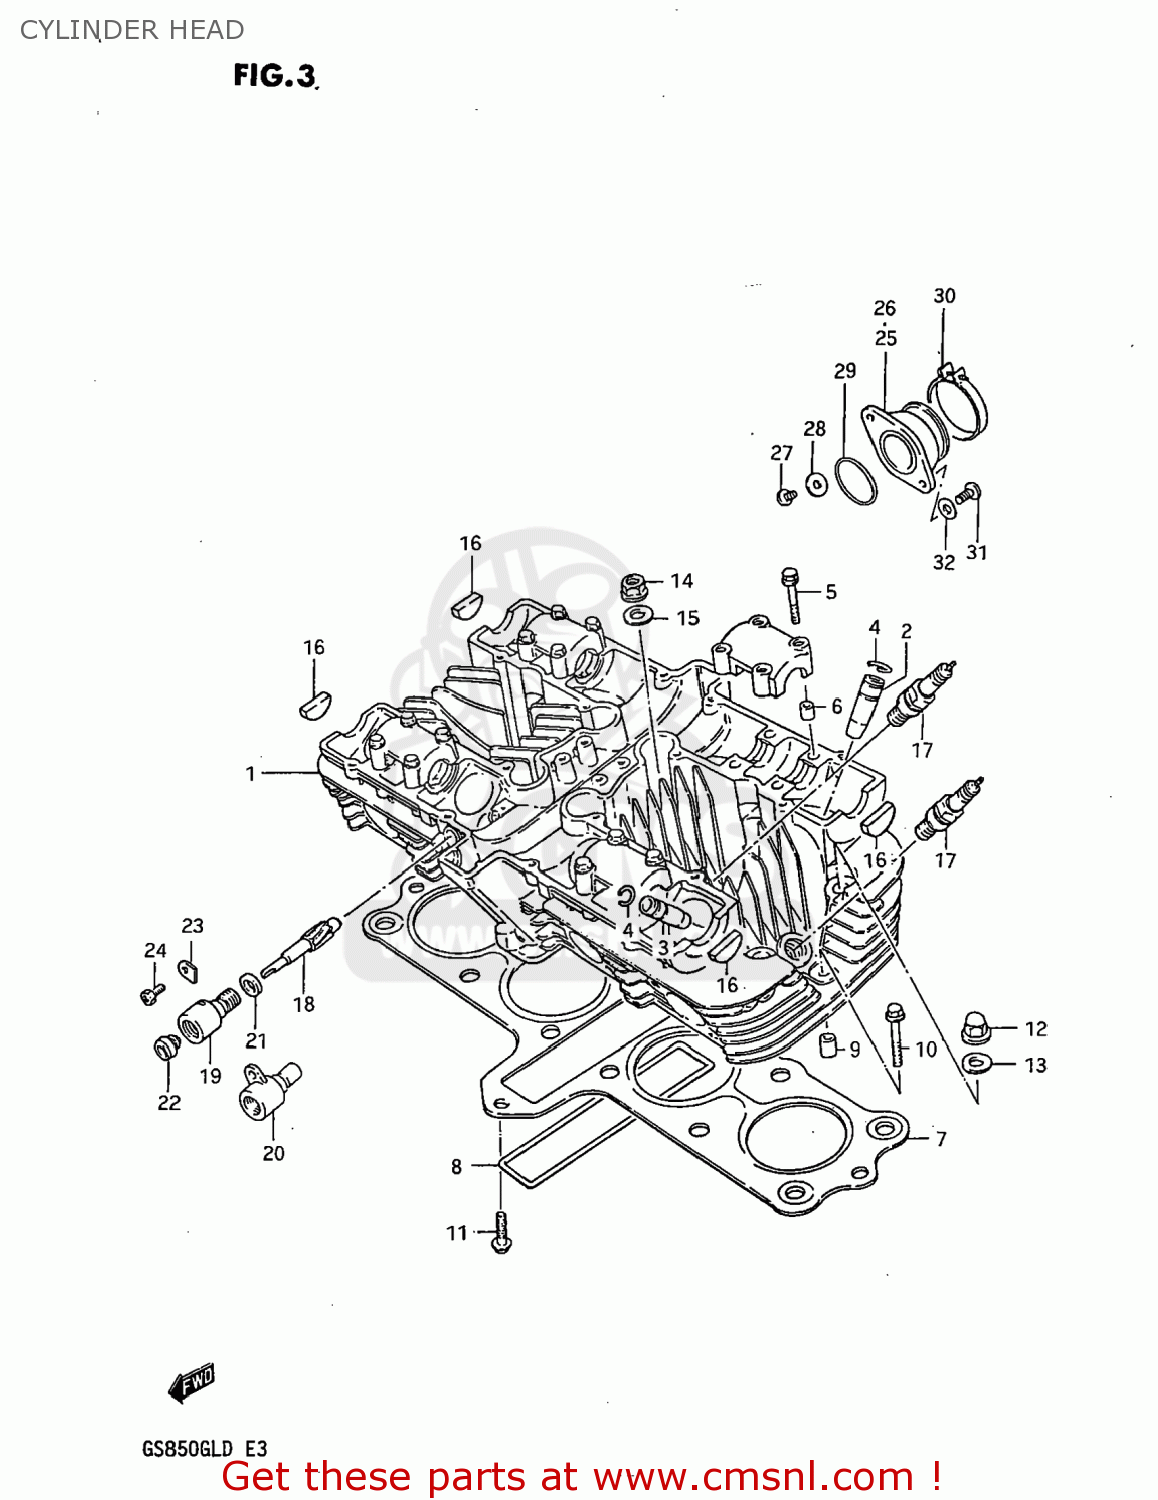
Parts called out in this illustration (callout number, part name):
1	HEAD ASSEMBLY,CYLINDER
2	GUIDE,INTAKE VALVE
3	GUIDE,EXHAUST VALVE
4	RING,SNAP
5	BOLT(6X39)
6	PIN(6.2X8X11)
7	GASKET,CYLINDER HEAD (MCA)
8	O RING(D:3,ID:26X157)
9	PIN
10	BOLT,UNDER
11	BOLT
12	NUT
13	GASKET (NAS)
14	NUT
15	WASHER(10.5X22X2.3)
16	PLUG
17	PLUG,SPARK
18	GEAR,TACHOMETER DRIVEN
19	SLEEVE,TACHOMETER DRIVE
20	SLEEVE,TACHOMETER DRIVE GEAR
21	SEAL,TACHOMETER DRIVEN
22	SEAL,OIL(5X12X8)
23	PLATE,TACH DRIVE GEAR SLEEVE
24	SCREW(5X12)
25	PIPE,INTAKE,R
26	PIPE,INTAKE,L
27	BOLT
28	GASKET(5.3X9.3X1.2) (NAS)
29	O-RING
30	CLAMP
31	SCREW
32	WASHER
